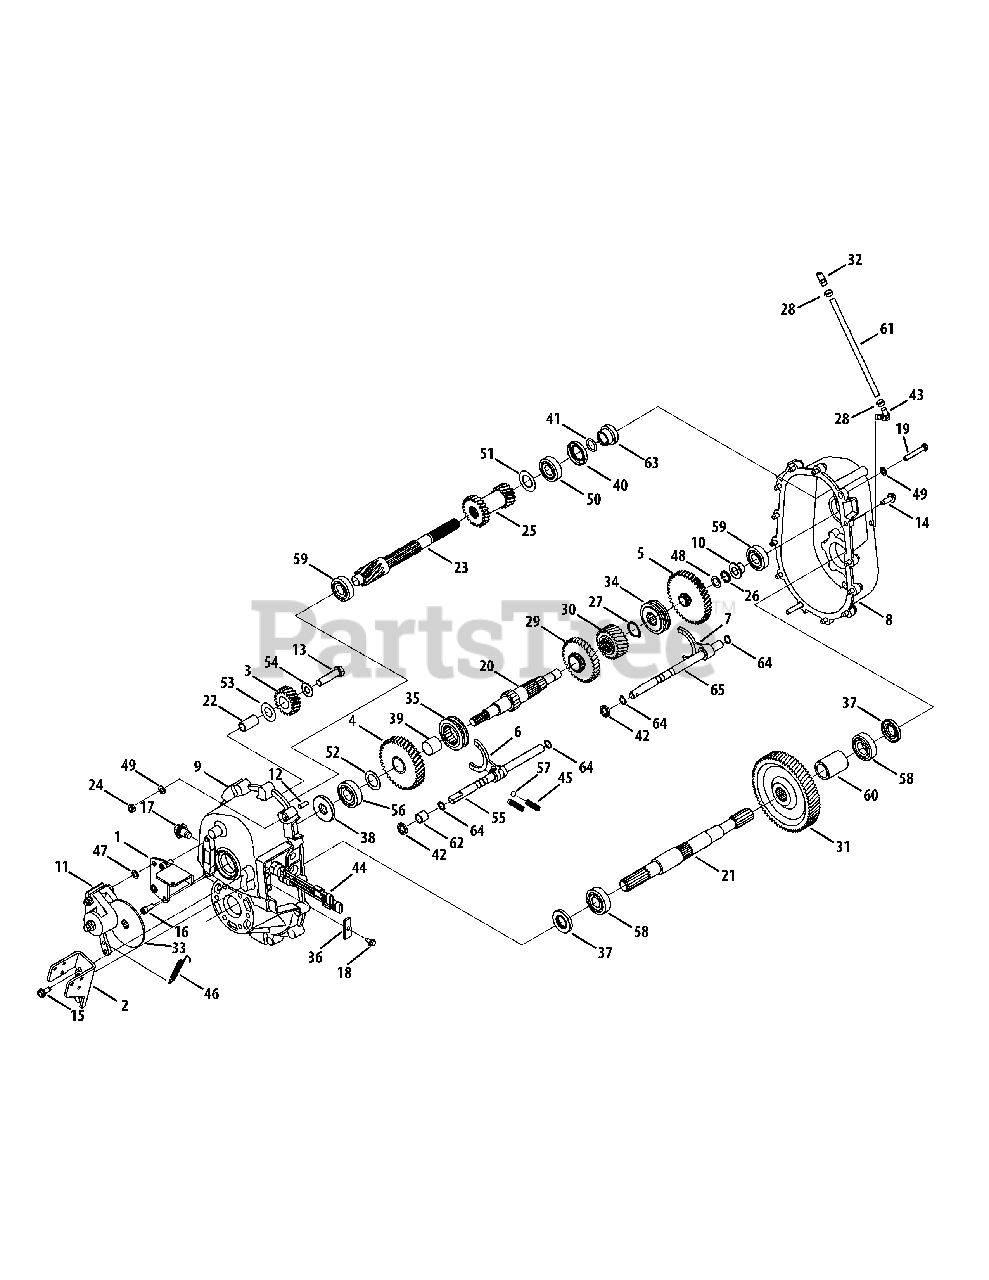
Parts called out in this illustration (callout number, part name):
1	Bracket Assembly, Painted
2	Bracket Assembly, Shift, Painted
3	Gear Assembly, Rev Idler
4	Gear, Rev, 39T
5	Gear Assembly, Low Speed
6	Yoke, Actr, Uv
7	Yoke Actr, Lo
8	Housing, Lh, Uv
9	Housing, Rh, Uv
10	Spacer, Flg, .630 x .787 x .662
11	Brake Assembly, Transfer Case
12	Dowel, Bush, .400 x .484 x .750
13	Hex Head Screw, 1/2-13, 2.00
14	Screw, Tt, 5/16-18, 1.000, Hxindwsh
15	Screw, Tt, 5/16-18, 0.750, Hxindwsh
16	Screw, Soc Hd, 5/16-18, .750
17	Screw, Plug, M14 x 1.5 x .36
18	Screw, Tt, 1/4-20 x .625, Hxindwsh
19	Hex Head Screw, 5/16-18, 2.00
20	Shaft, Mid, Transfer Case
21	Shaft, Output, Transfer Case
22	Shaft, Rev Idler
23	Shaft, Input, Transfer Case
24	Nut, Hex Lock, 5/16-18, Ctrlk
25	Gear, Pinion, Input Forward
26	External Snap Ring .625 Dia.
27	Ring, Retainer, 1.125 Dia.
28	Hoase Clamp, .490 Dia.
29	Gear, High, 33t
30	Gear, Final Pinion, 22t
31	Gear, Final, 73t
32	Vent, 3/8 Dia.
33	Disc, Brk, Uv
34	Collar, Lo
35	Collar, Hi-rev, 4x4
36	Plate, Detent Spring
37	Seal, Oil, 25x46x7
38	Seal, Oil, 20x52x7
39	Bearing, 25mm x 28mm x 25mm
40	Seal, Oil, 35 x 47 x 7
41	O-ring, .924 Id x .103
42	Seal, Oil, .563 x .875 x .188
43	Fitting, 90 degree Elbow
44	Switch, Saf, Neut (4x4 Only - Qty. (2).
45	Spring, 3/8 Od x 1 1/4 Lg
46	Spring, Extn, .38 Od x 3.9 Lg
47	Washer, Flat, .385 x .620 x .033
48	Washer, Flat, .635x.930x.033, Ht
49	Washer, Flat, .330 x .630 x .0635
50	Bearing, Ball, 25 x 62 x 17, 6305
51	Spacer, 1.275 x 1.00 x .085
52	Washer, Flat, 1.007x1.542x.03, Ht
53	Washer, Thrust, .757 x 1.38 x .062
54	Washer, Flat, .51 x 1.12 x .06, Ht
55	Shaft, Actr, Fwd, Rev
56	Bearing, Ball, .79 Id x 2.05 Od x .6
57	Ball, Detent, .375
58	Bearing, Ball, 25x52x15, 6205
59	Bearing, Ball, 20x47x14, 6204
60	Spacer, Output Shaft
61	Fuel Line, 5/16 Id
62	Spacer, .566 x .725 x .650
63	Spacer, Input, Uv, Transfer Case
65	Shaft, Actr, Lo
